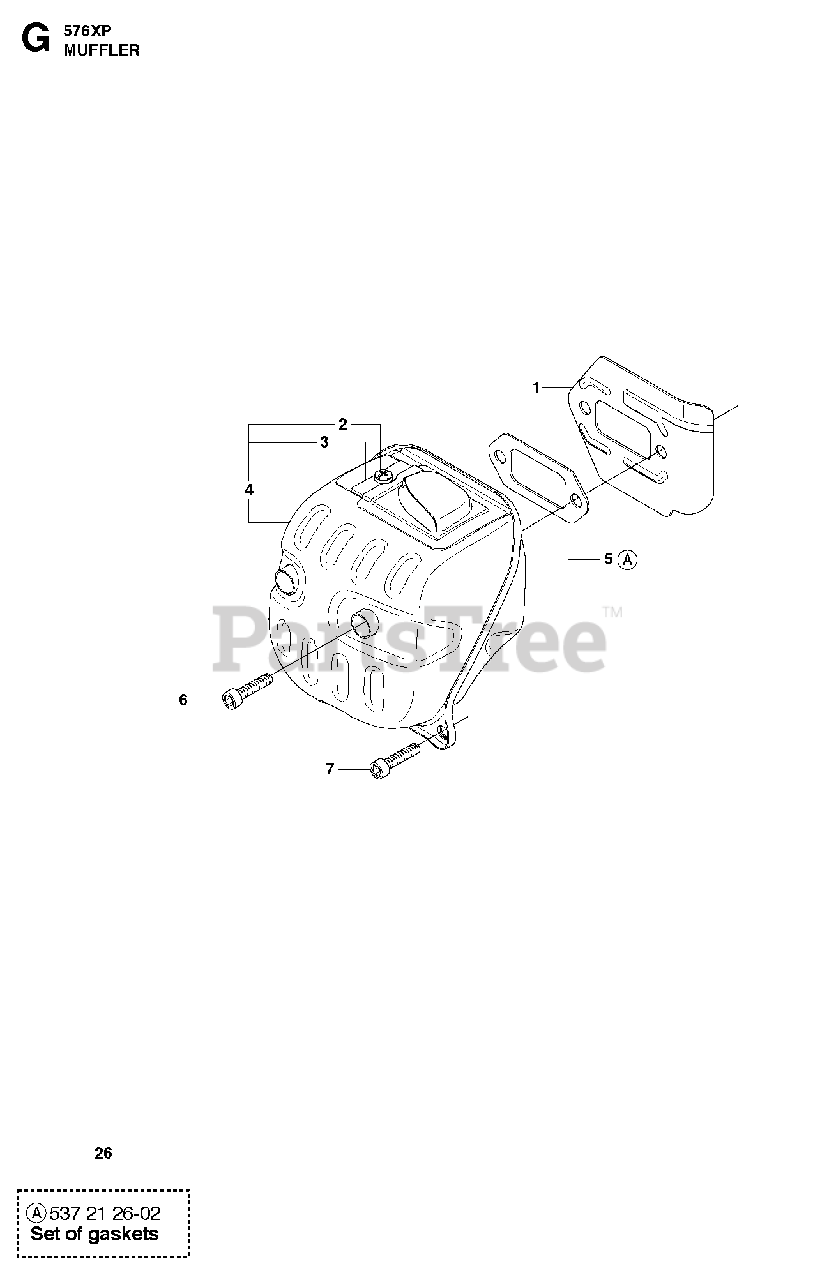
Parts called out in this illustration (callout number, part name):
2	SCREW
3	SCREEN
4	MUFFLER ASSY (FF CE)
4	MUFFLER ASSY (DF US)
5	GASKET
6	SCREW MC6S 6X20
26	GASKET KIT
